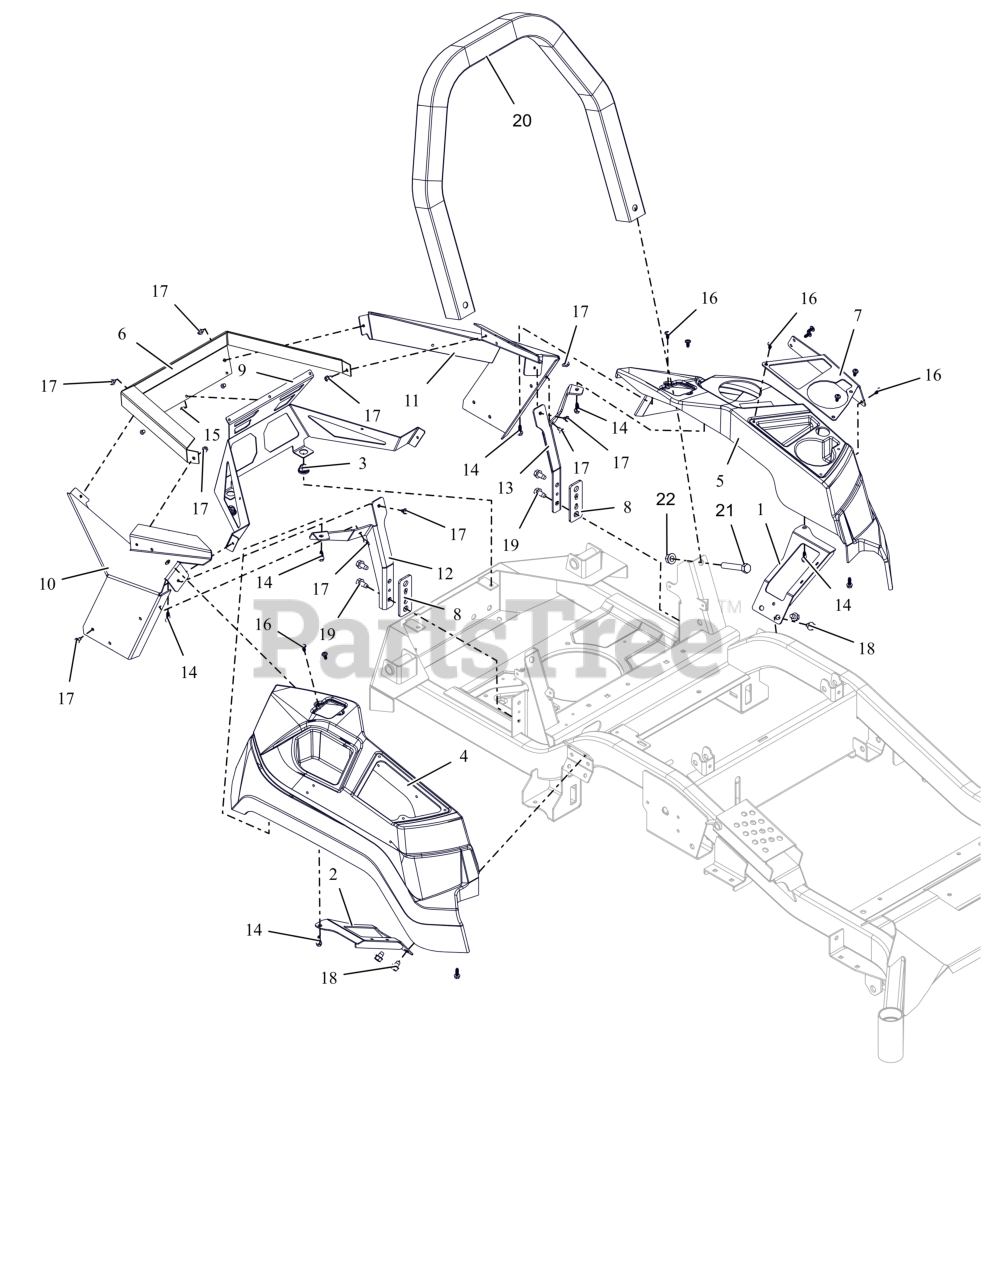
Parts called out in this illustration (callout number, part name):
1	WLDMT, LH FENDER MOUNT
2	WLDMT, RH FENDER MOUNT
3	GROMMET, 10MM BOLLHOFF
4	FENDER, RH APEX - 2017
5	FENDER, LH APEX
6	GUARD,ENGINE WRAP
7	PLATE, APEX CUP HOLDER COVER
8	PLATE, CONTROL PANEL SPACER
9	GUARD, ENGINE
10	PANEL, RH REAR FENDER MOUNT
11	PANEL, LH REAR FENDER MOUNT
12	BRKT, RH FENDER MTG (ORANGE)
13	BRKT, LH FENDER MOUNT (ORANGE)
14	SCR, PLASTITE .25-10X.75 ZCC
15	RIVET, .1875 AL/AL .126-.250
16	SCR-PAN .25-15X.50 6L H/LZB500
17	SCR,TAP .25-20X.375 HWH TR ZCC
18	SCR,TAP .375-16X.50 HWH TR ZCC
19	SCR,TAP .375-16X.75 HWH TR ZCC
20	GUARD, ENGINE -TOP (ORANGE)
21	BLT, HEX .50-13X3.00 G5 ZCC
22	NUT-LK-CTR-FLG .500-13 GG ZCC
